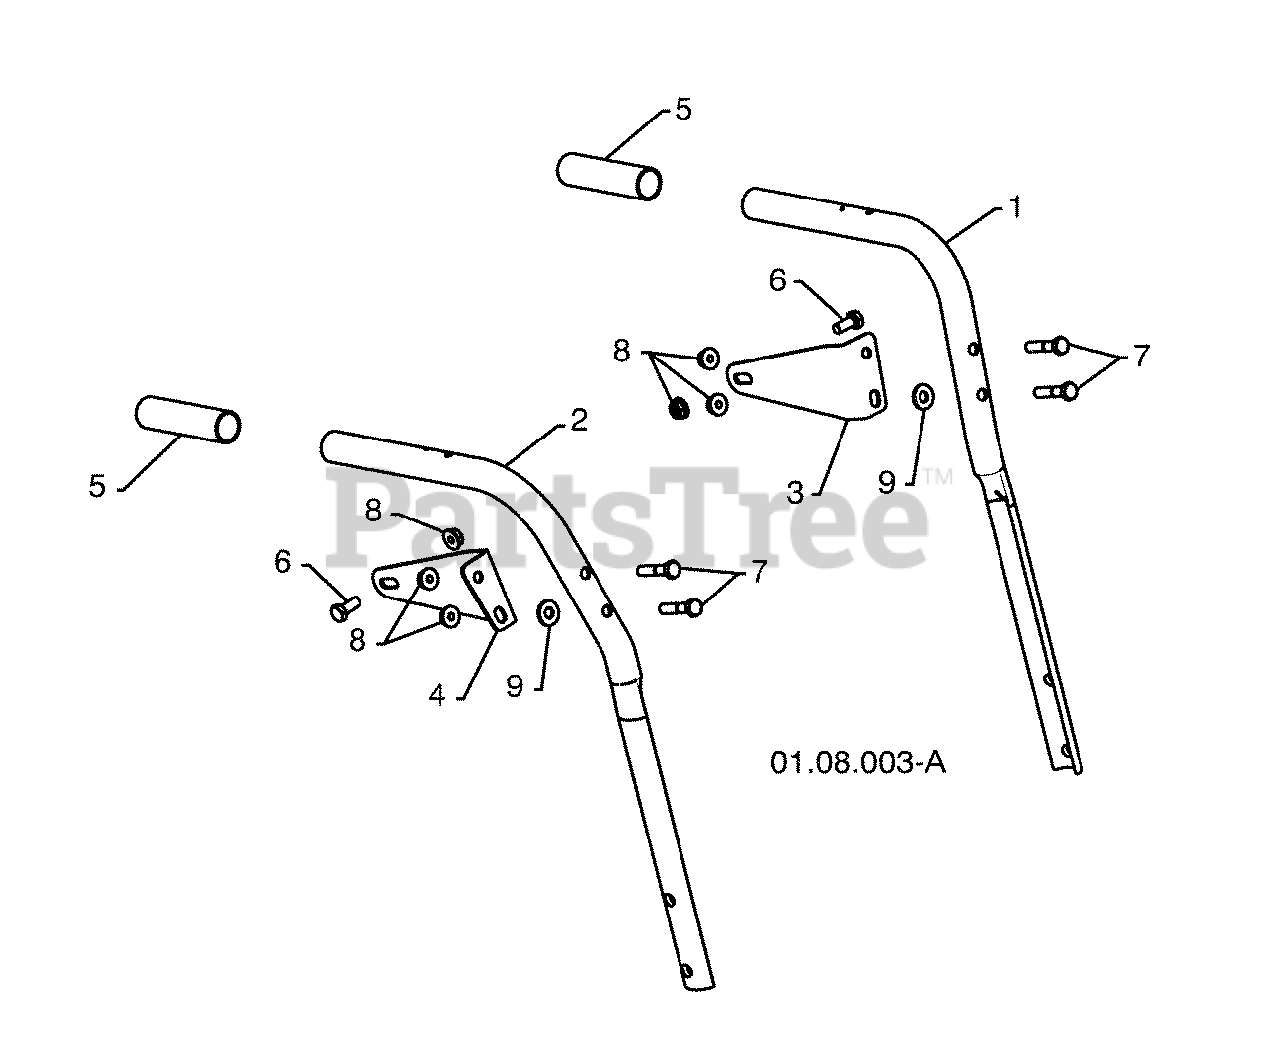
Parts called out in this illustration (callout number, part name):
1	PLOW HANDLE LH
2	PLOW HANDLE RH
3	PANEL BRACKET LH
4	PANEL BRACKET RH
5	HANDLE GRIP
6	SCREW 5/16--18 X .750
7	SCREW 5/16--18 X 1.50
8	NUT 5/16--18
